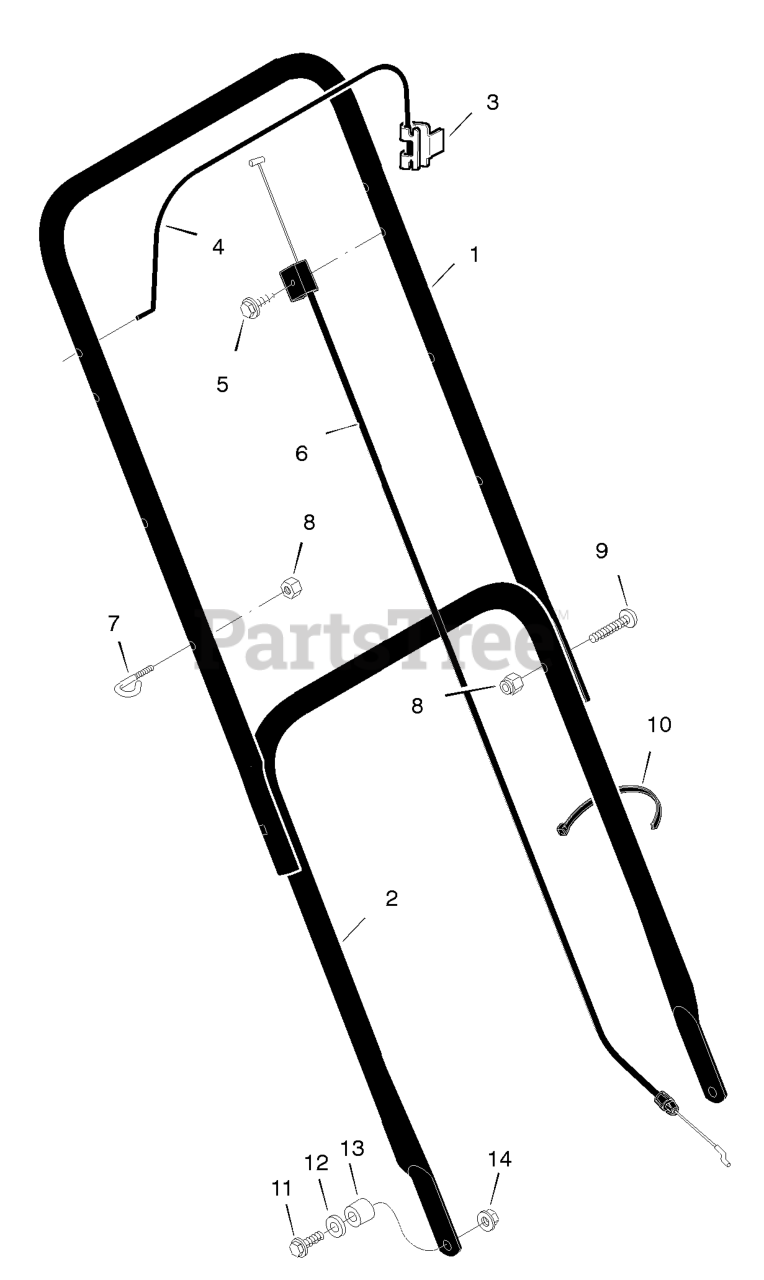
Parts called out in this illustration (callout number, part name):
1	Handle, Upper (Black)
2	Handle, Lower (Black)
3	Bracket, Stop Lever
4	Lever, Stop
6	Engine Stop Cable
7	GUIDE, ROPE
8	Locknut
10	Fastener, Cable
11	Bolt
14	Nut
